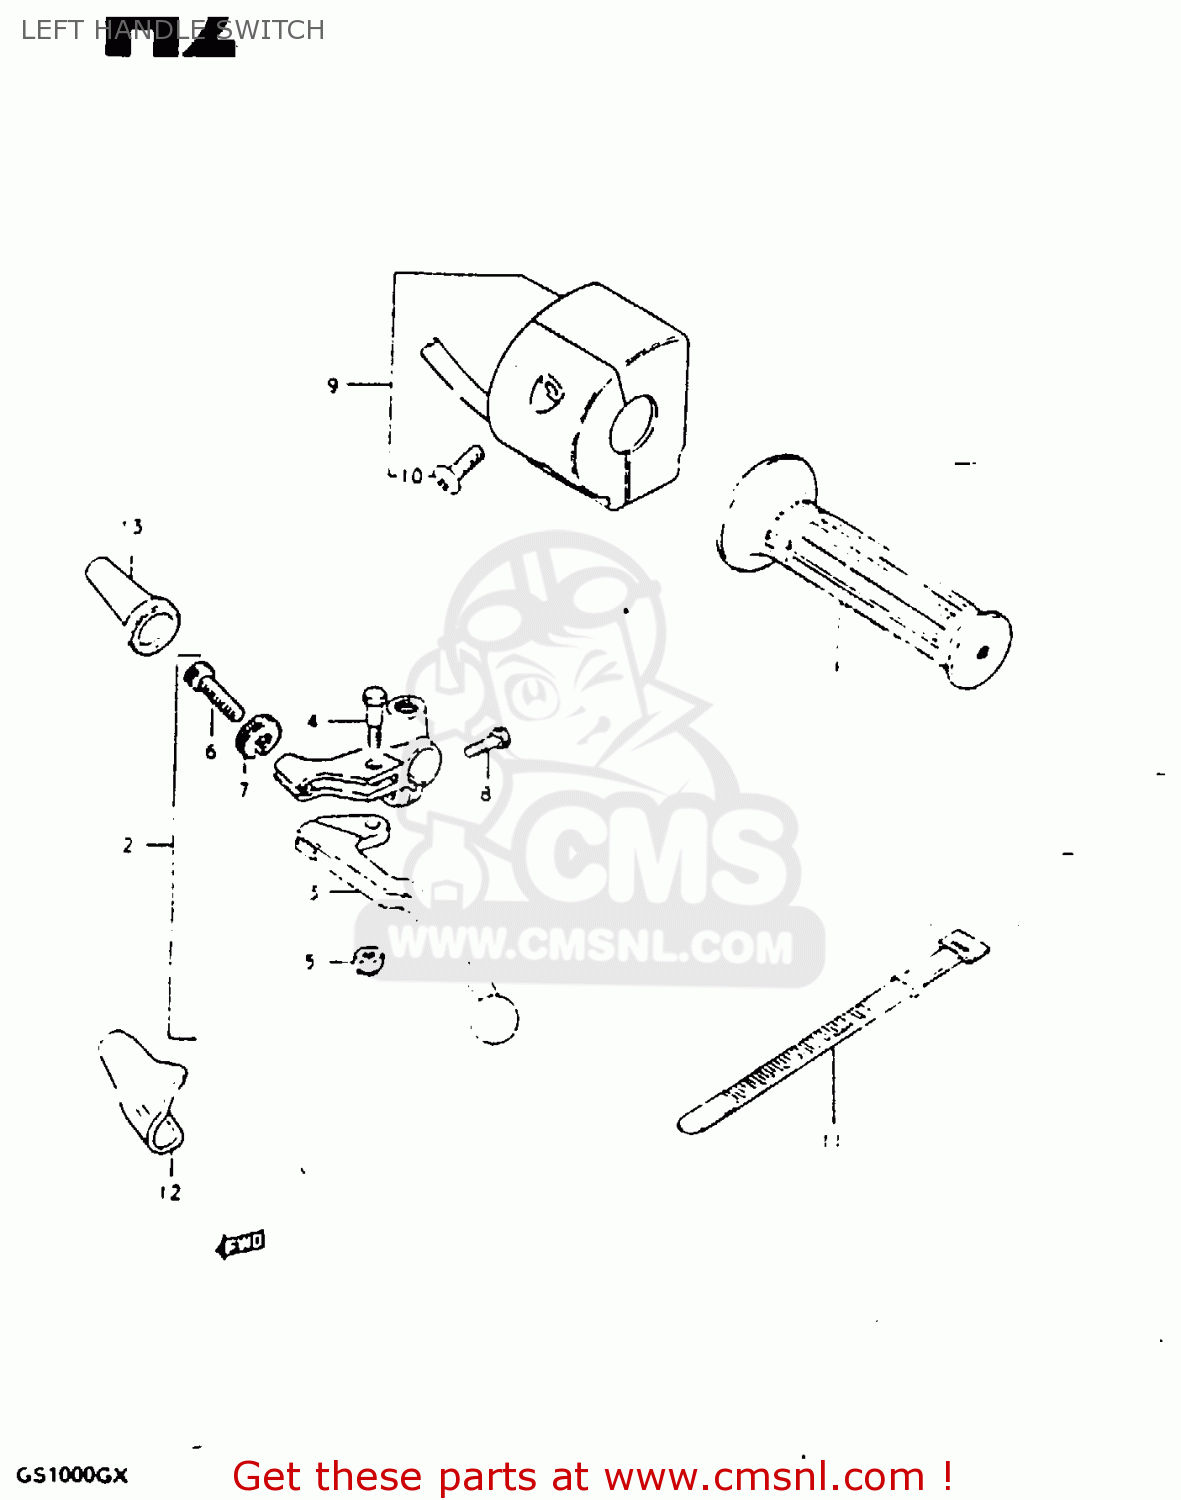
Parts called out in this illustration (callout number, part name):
1	GRIP,LEFT
2	LEVER ASSY, CLUTCH
3	LEVER,CLUTCH
4	BOLT,LEVER
5	NUT 6MM
6	ADJUSTER,CABLE
7	NUT,CABLE ADJUSTER
8	BOLT
9	SWITCH ASSY, HANDLE LH
10	SCREW
11	CLAMP(L:120)
12	COVER,CLUTCH LEVER
13	BOOT,CLUTCH CABLE
